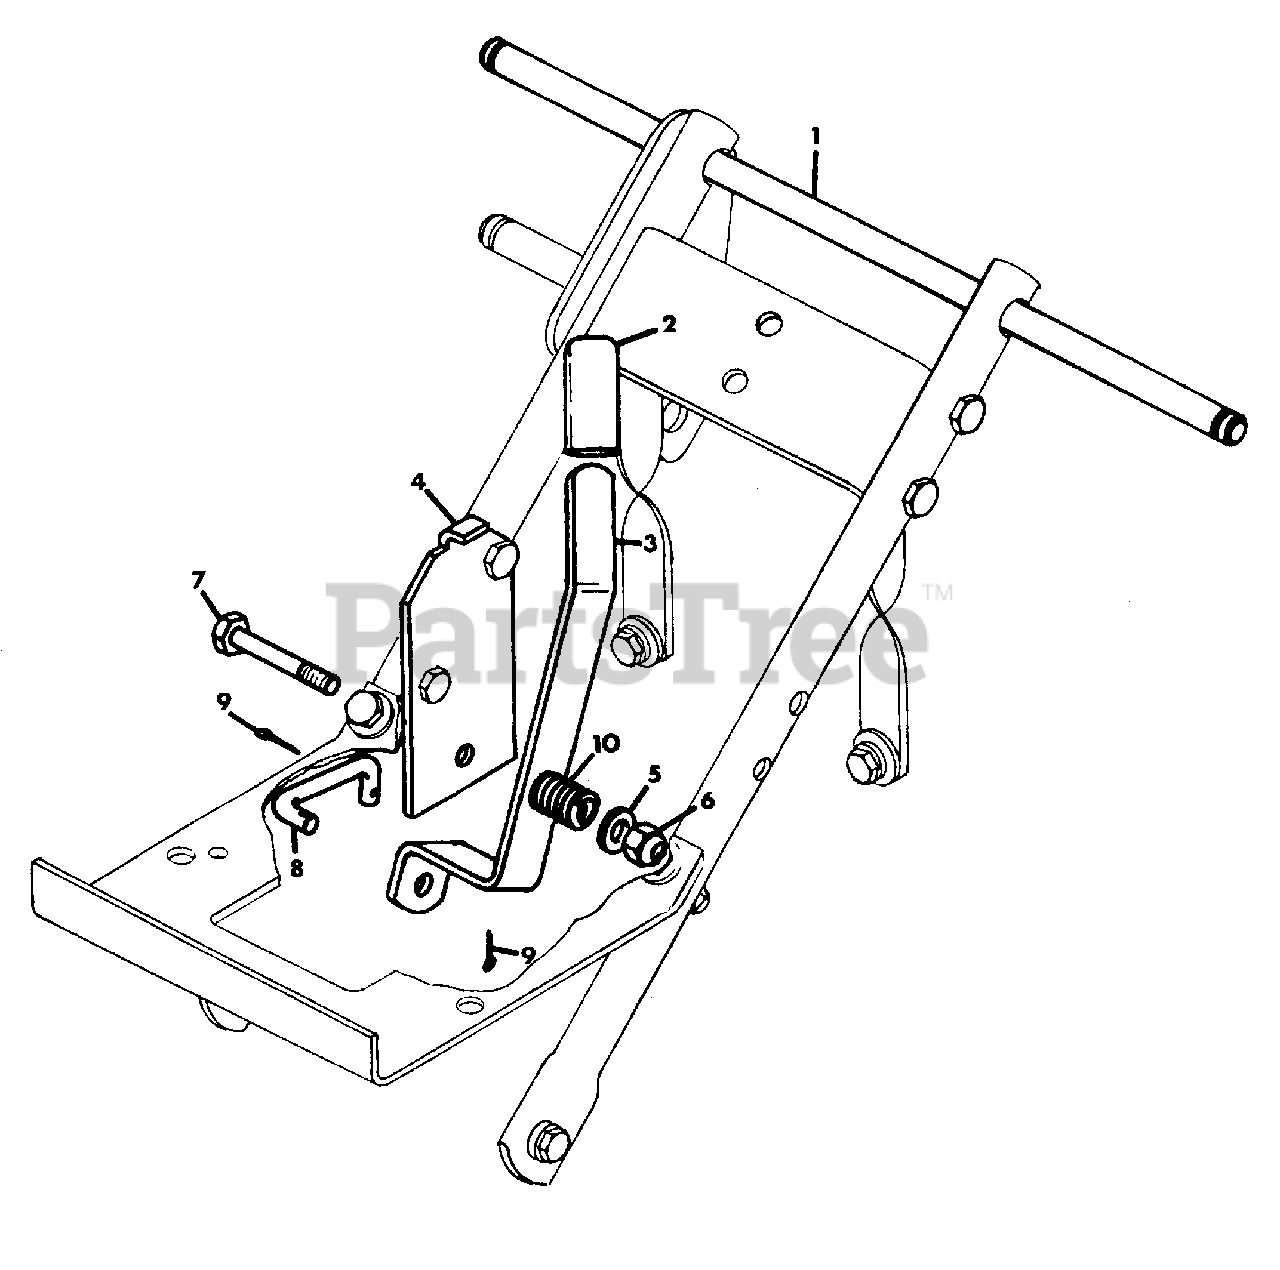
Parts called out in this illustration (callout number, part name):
1	SHAFT, CROSS
2	GRIP, HANDLE
3	LEVER, HI-LO
4	BRACKET, HI-LO
5	WASHER, FLAT .406X.812X.065
6	NUT, LOCK 3/8-16
7	BOLT, HEX 3/8-16X1.75
8	ROD, HI-LO
9	PIN, COTTER .09X1.00
10	SPRING, COMP. 1X.78
